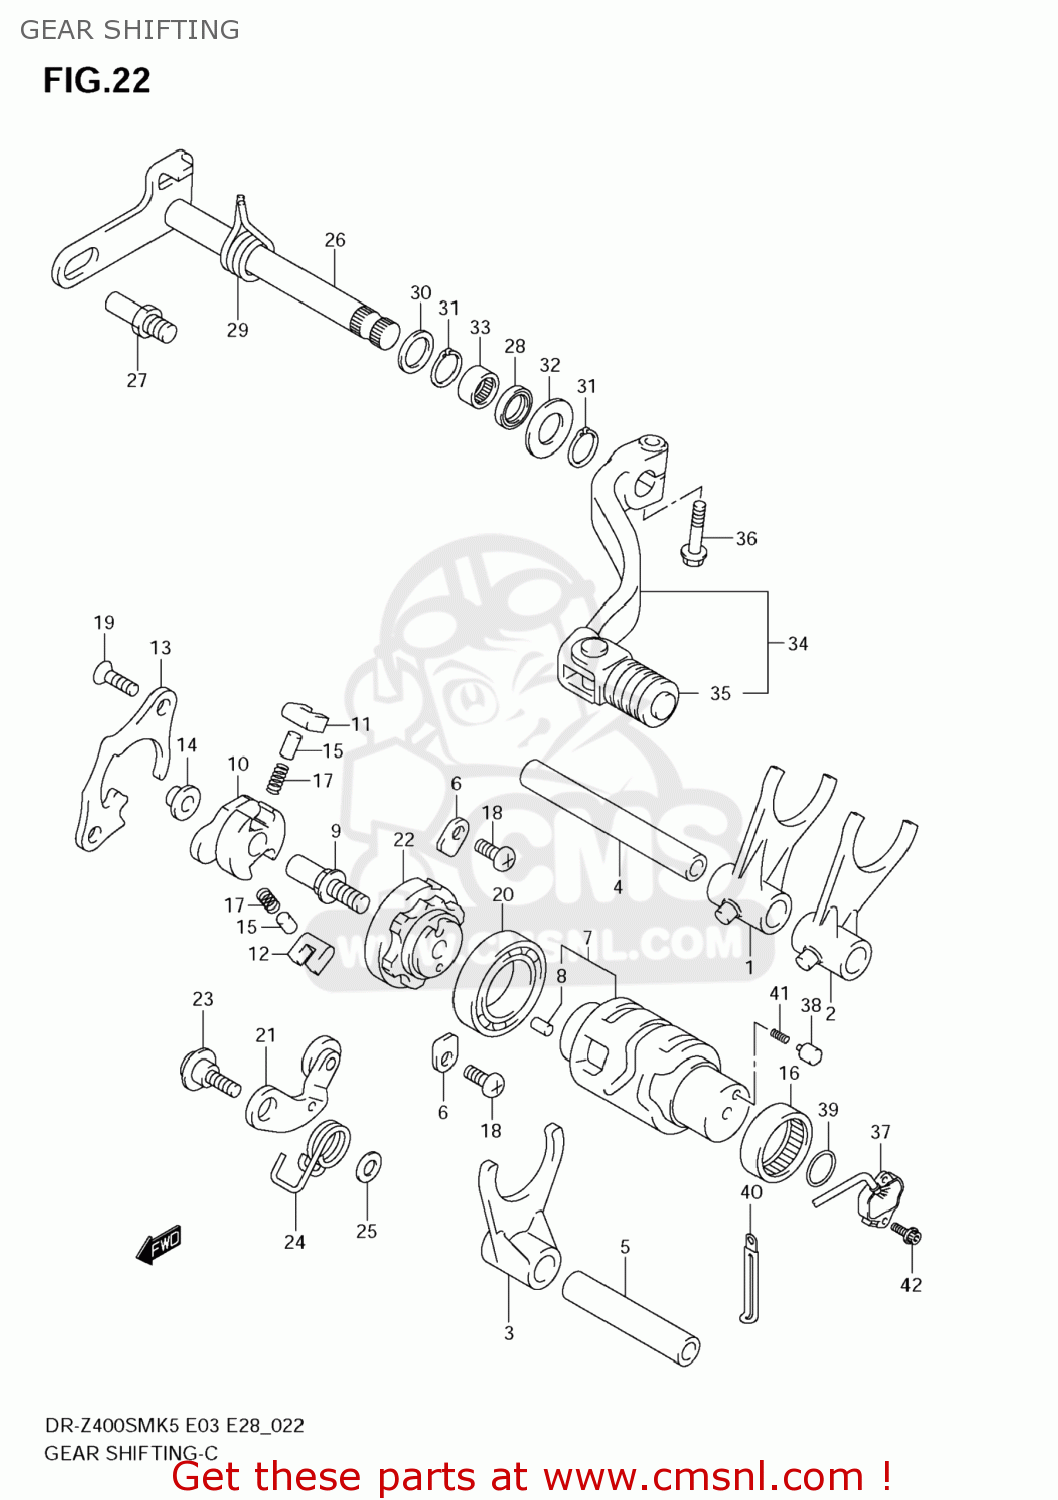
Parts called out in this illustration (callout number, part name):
1	FORK,GEAR SHIFT NO.1
2	FORK,GEAR SHIFT NO.2
3	FORK,GEAR SHIFT NO.3
4	SHAFT,GEAR SHIFT FORK(L:95)
5	SHAFT,GEAR SHIFT FORK(L:60)
6	RETAINER
7	CAM,GEAR SHIFT
8	PIN
9	PIN,SHIFT CAM DRIVEN GEAR
10	SHIFTER,GEAR SHIFT CAM
11	PAWL,GEAR SHIFT NO.1
12	PAWL,GEAR SHIFT NO.2
13	LIFTER,GEAR SHIFT PAWL
14	SPACER(7X10X5)
15	PIN(5X8)
16	BEARING(25X32X12)
17	SPRING
18	BOLT(6X12)
19	SCREW(6X12)
20	BEARING
21	STOPPER,GEAR SHIFT CAM
22	PLATE,GEAR SHIFT STOPPER
23	BOLT,CAM STOPPER ARM
24	SPRING,SHIFT CAM STOPPER
25	WASHER
26	SHAFT,GEAR SHIFT
27	STOPPER,SHIFT ARM
28	SEAL,OIL(14X22X6)
29	SPRING
30	SHIM(14X20X1)
31	CIRCLIP
32	WASHER
33	BEARING(14X20X12)
34	LEVER,GEAR SHF
35	RUBBER,GEAR SHIFT PEDAL
36	BOLT
37	BASE ASSY,GEAR SHIFT TERMINAL
38	PIN(5X15.5)
39	O RING(D:2.4,ID:26.2)
40	CLAMP(L:45)
41	SPRING
42	BOLT
